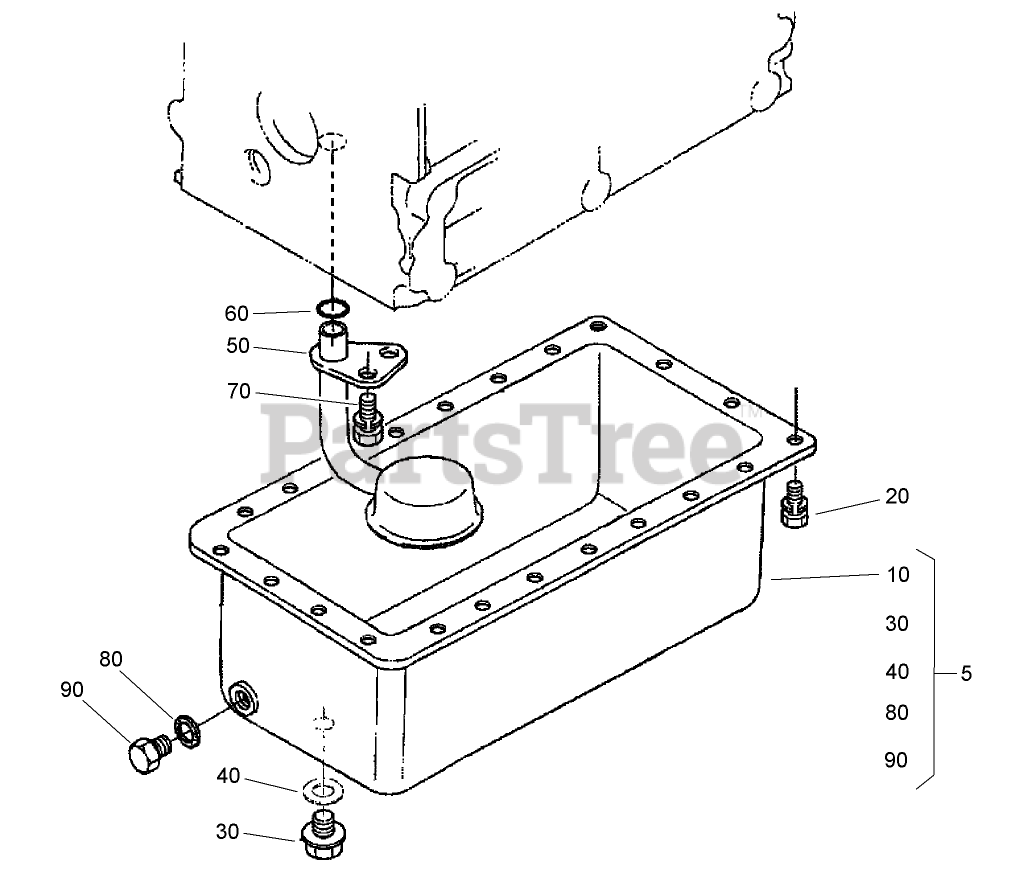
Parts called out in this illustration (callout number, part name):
5	OIL PAN ASM
10	PAN-OIL
30	PLUG-DRAIN
40	GASKET
50	STRAINER-PICKUP, OIL
60	O-RING
80	GASKET
90	PLUG-DRAIN
